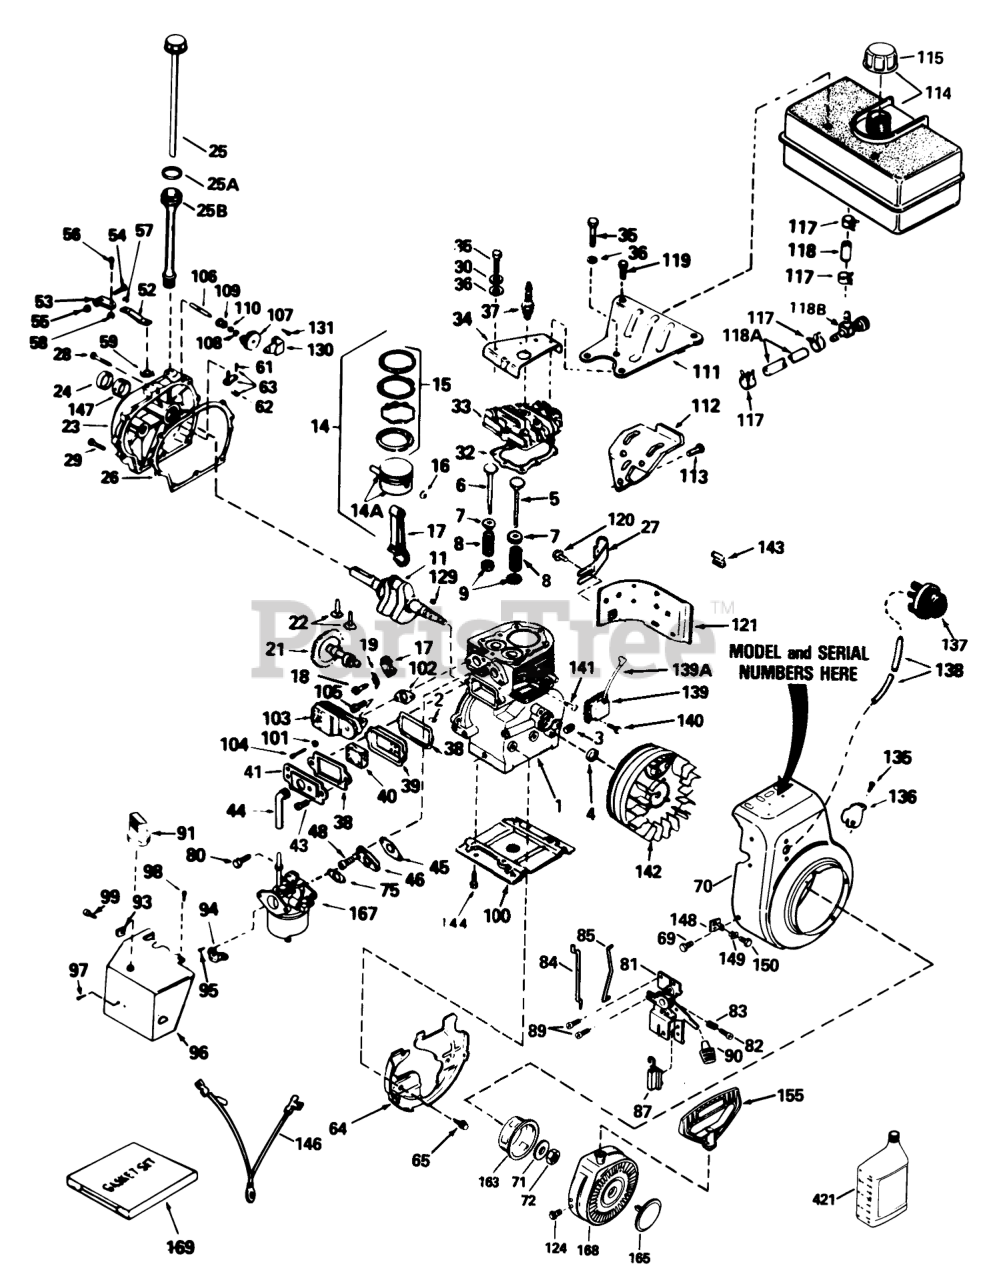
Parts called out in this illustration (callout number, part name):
1	Cylinder Assembly (Incl. ref. #2, 3, & 4)
2	Pin-Dowel
3	Plug-Drain, Oil (SQH 1/4-18)
4	Oil Seal
5	Valve-Intake, Standard (Incl. ref. #9)
6	Valve-Exhaust, Standard (Incl. ref. #9)
7	Cap-Spring, Valve
8	Spring-Valve
9	Keeper-Spring, Valve
11	Crankshaft
14	Piston-Pin & Ring Assy. Standard (Incl. ref. #14A, 15 & 16)
14A	Piston & Pin Assy. Standard (Incl. ref. #16)
15	"O"Ring
16	Ring-Retaining, Piston Pin
17	Connecting Rod Assembly (Incl. ref. #18 & 19)
18	Bolt-Connecting Rod
19	Dipper-Oil
21	55012A GIL SNWTHWR
22	Lifter-Valve
23	Cover-Cylinder (incl. ref. #24, 24A, 106, 147)
24	Oil Seal
25	Dipstick
25B	Tube-Fill, Oil
26	Gasket-Cover, Cylinder
27	Clip-Tube, Fill
28	Screw (1/4-20 x 1-1/4)
30	Washer-Belleville
32	Gasket-Cylinder Head
33	Head-Cylinder (Incl. 3 of ref. #35)
34	Cover-Head, Cylinder
35	Screw (5/16-18 X 2-1/2)
36	Washer-Flat
37	Spark Plug-Resistor (R J19 L M)
38	Gasket-Cover, Valve
39	Body-Breather
40	Element-Breather
41	Cover-Valve
44	Tube-Breather
45	Gasket-Pipe, Intake
46	Flange-Carburetor (Incl. ref. #80)
52	Lever-Governor
53	Clamp-Lever, Governor
55	Nut-Lock
56	Screw
57	Washer-Lock
58	Nut-Lock
59	Ring-Retaining
61	Screw (6-40x5/16)
62	Yoke-Governor
63	Rod Assy.-Governor (Incl. ref. #61 & 62)
64	Baffle-Blower Housing
65	Screw (1/4-20x19/32)
70	Blower Housing
71	Washer-Belleville
72	Flywheel Nut
75	Gasket-Carburetor
80	Screw (T-30, 1/4-20 X 27-32)
81	Control Assy.-Speed (Incl. ref. #82, 83, 86 & 87)
82	Screw
83	Spring-Compression
84	Governor Link
85	Link-Throttle
87	Terminal
89	Screw (10-32 x 1/2)
90	Knob-Control
91	Knob-Choke
93	Nut-U Type
94	Bracket-Choke
95	Screw (10-32 x 1/2)
96	Carburetor Cover
97	Screw (8-32 X 5/16)
98	Screw (10-32x1/2)
99	Screw (8-32 x 3/8)
100	Base Engine
102	35865 Gasket-Muffler
103	Muffler
104	Screw (5/16-18 X 2)
106	Shaft-Governor
107	Gear Assy.-Governor (Incl. ref. #110)
108	Ring-Retaining
109	Spool-Governor
110	Washer-Flat
111	Bracket-Fuel Tank
112	Bracket-Fuel Tank
113	Screw (1/4-20x19/32)
114	Tank Assembly-Fuel (incl. ref. #115 & 117)
115	Cap-Fuel
117	Clamp-Line, Fuel
118	Line-Fuel
118A	Line-Fuel (8.62)
118B	Valve-Shut Off, Fuel
119	Screw (1/4-15x7/8)
121	Extension-Blower Hsng.
124	Screw, Hex Hd.
129	Key-Flywheel
130	Bracket, Governor
131	Screw (10-24x1/2)
135	Screw (8-32 x 3/8)
137	Primer-Asm
138	Line-Primer
139	Solid State
139A	Cover-Spark Plug
140	Screw
141	Stud
142	Flywheel
143	Clip-Wire
146	Ground Wire
147	Bushing-Crankshaft
148	Bracket
149	Grommet
150	Screw (8-32 x 3/8)
155	Handle-Starter, Mitten Grip
163	Cup-Starter
165	Plug Starter
167	Carburetor (Incl.ref. #75)
168	Rewind Starter
169	Gasket Set
421	Oil-Engine (SAE 5W30)
